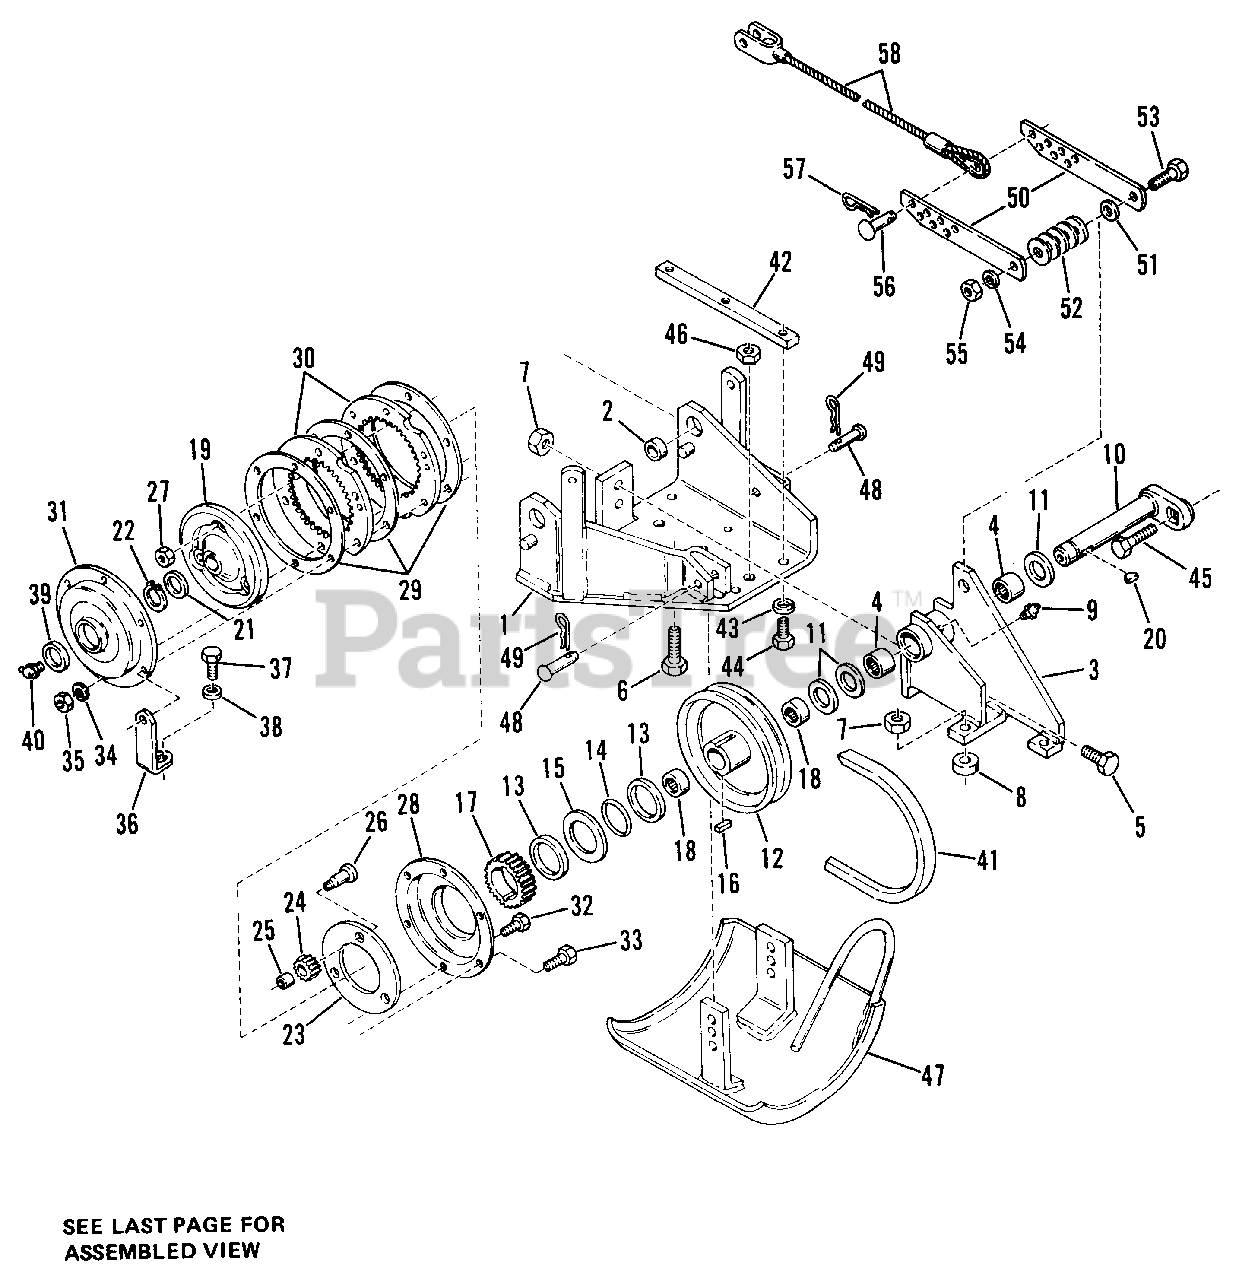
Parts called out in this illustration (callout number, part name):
1	Mounting Plate Assembly
3	Bearing Housing
5	Hex Head Capscrew, 7/16"-14 x 1-1/4"
6	Hex Head Capscrew
7	Full Hex Lock Nut, 7/16"-14
9	Grease Fitting
10	Crankshaft
12	Hub and Pulley
19	Spider Hub
20	Woodruff Key, No. 9
22	Retaining Ring
23	Ring, Bolt
25	Needle Bearing
26	Pinion Pin
27	Full Hex Lock Nut, 5/16"-18
28	Left Hand Cover
30	Ring Gear
32	Hex Capscrew, 5/16"-18 x 3/4"
33	Hex Capscrew, 5/16"-18 x 7/8"
34	Lockwasher, 5/16"
35	Hex Full Nut, 5/16"-18
37	Hex Capscrew, 5/16"-18 x 1"
38	Plain Washer, 1/4"
40	Grease Fitting
42	Spacer Bar
43	Lockwasher, 5/16"
44	Hex Head Capscrew, 5/16"-18 x 7/8"
45	Hex Head Capscrew
46	Full Hex Lock Nut
47	Shoe Assembly
49	Spring Clip
51	Pinion Spacer
53	Hex Head Screw, 3/8"-16 x 1-1/2"
54	Lockwasher, 3/8"
55	Full Hex Nut, 3/8"-16
57	Spring Clip
58	Cable Assembly
